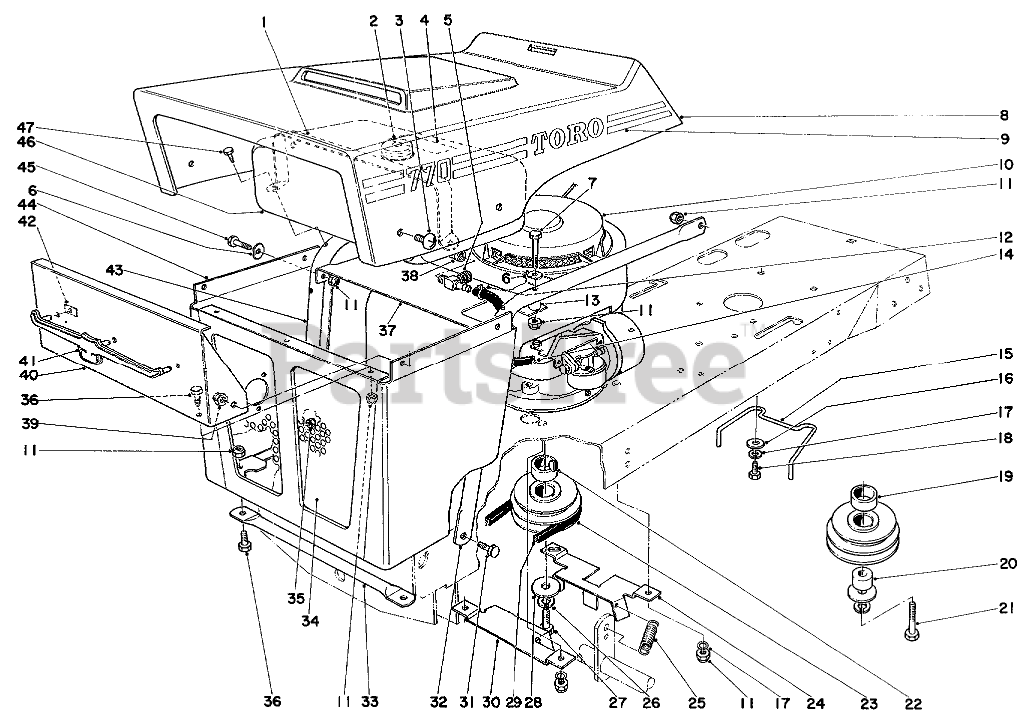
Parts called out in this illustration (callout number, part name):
1	Strap Gas Tank
2	Gas Cap
3	Round Head Screw
4	Decal
5	Shut Off Valve
6	WASHER
7	SCREW-HH
9	Decal Left, Model 57111
10	Engine Model V70-125148
11	NUT-LOCK, CONE
12	CLAMP-HOSE
13	Spacer
15	Belt Retainer
16	WASHER-PLAIN
17	WASHER-LOCK/SP
18	SCREW-HH
19	Spacer
20	Spacer (use with model V70-125130 engine)
21	SCREW-HH
22	WASHER-LOCK
23	Engine Pulley
24	Belt Guide
25	Spring Tension
26	WASHER-LOCK
27	SCREW-HH
28	Washer
29	ENGINE BELT
30	Belt Guide
31	SCREW-HH
32	Support Gas Tank, Left
33	Rod Grille Mount
34	Grille Panel
35	NUT-LOCK, SIDE
36	SCREW-HH
37	Tray Gas Tank
38	Elbow
39	NUT-LOCK, CONE
40	Panel Grille
41	Bullshead
42	Timmerman Nut
43	Support Gas Tank, Right
44	Grille
45	SCREW-HH
46	Gas Tank
47	Self-Tapping Screw
